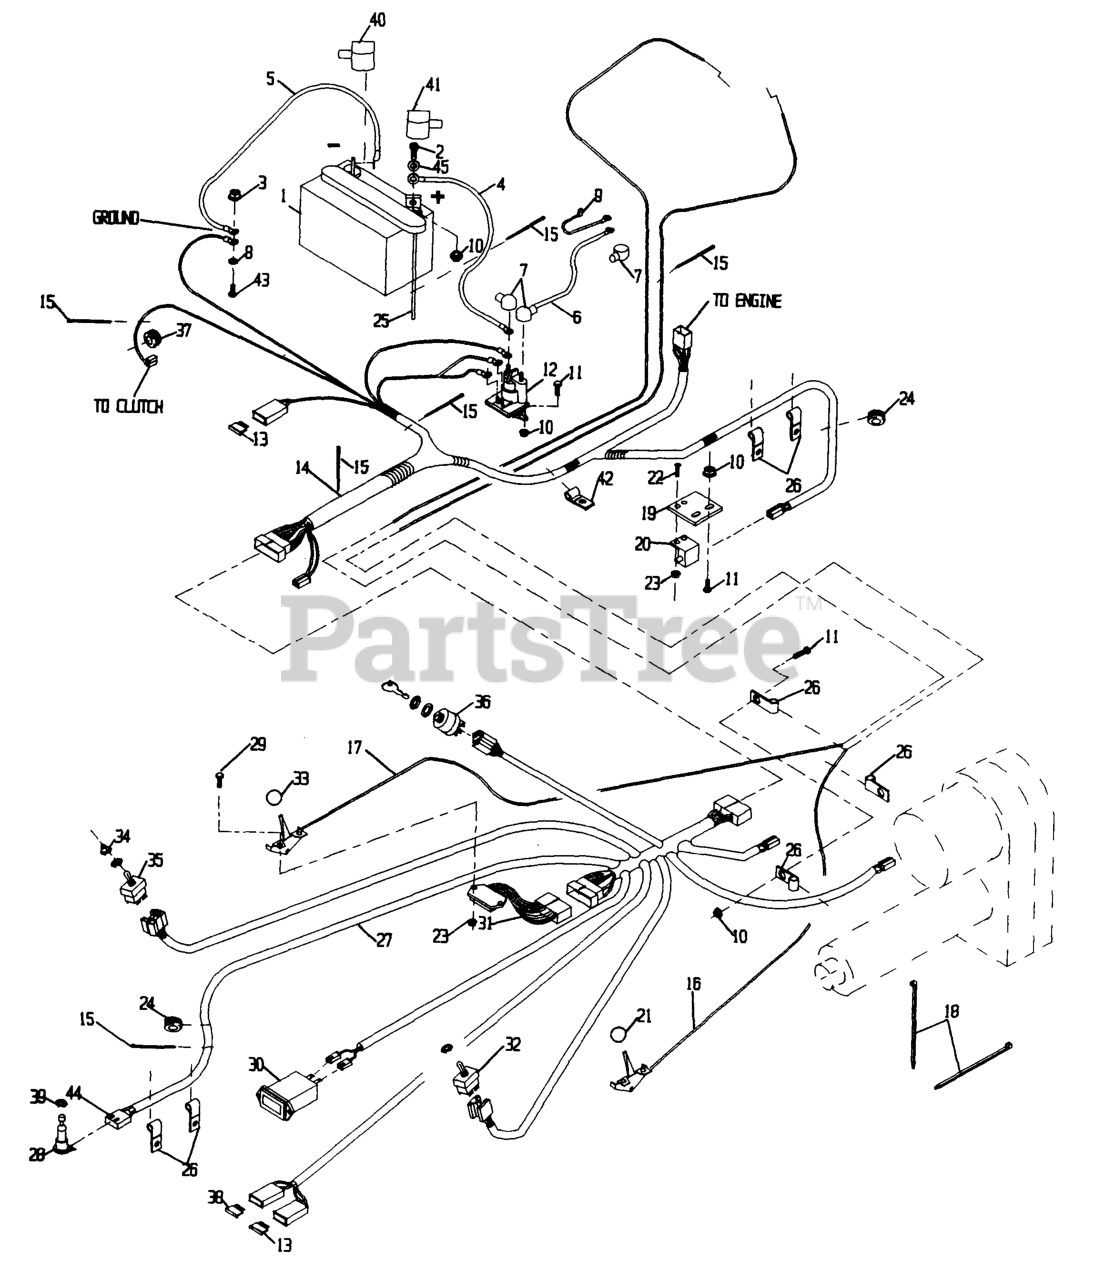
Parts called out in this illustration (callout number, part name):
1	Battery, 12 Volt
5	WIRE-GROUND
6	WIRE,BATTERY POSITIVE
7	INSULATOR-SOLENOID
8	WASHER-SPRING
13	FUSE-BLADE TYPE, 20 AMP
15	TIE-CABLE
16	THROTTLE CABLE ASM
18	TIE-PLASTIC
19	BRACKET,SAFETY SWITCH
20	SWITCH-OPEN, NORMALLY
21	KNOB-BALL
24	GROMMET
26	CLIP-LOOM
28	SWITCH,PUSH BUTTON
30	METER-HOUR
31	MODULE,OPC
32	SWITCH,W/TERM CLIPPD
33	KNOB-BALL, BLACK
34	BOOT-SWITCH, TOGGLE
35	SWITCH-TOGGLE, DPDT
36	SWITCH,IGNITION
37	GROMMET
38	FUSE-BLADE TYPE, 30 AMP
41	INSULATOR, BATTERY -
42	CLIP-LOOM
44	CONNECTOR,PACKARD 2 WAY
